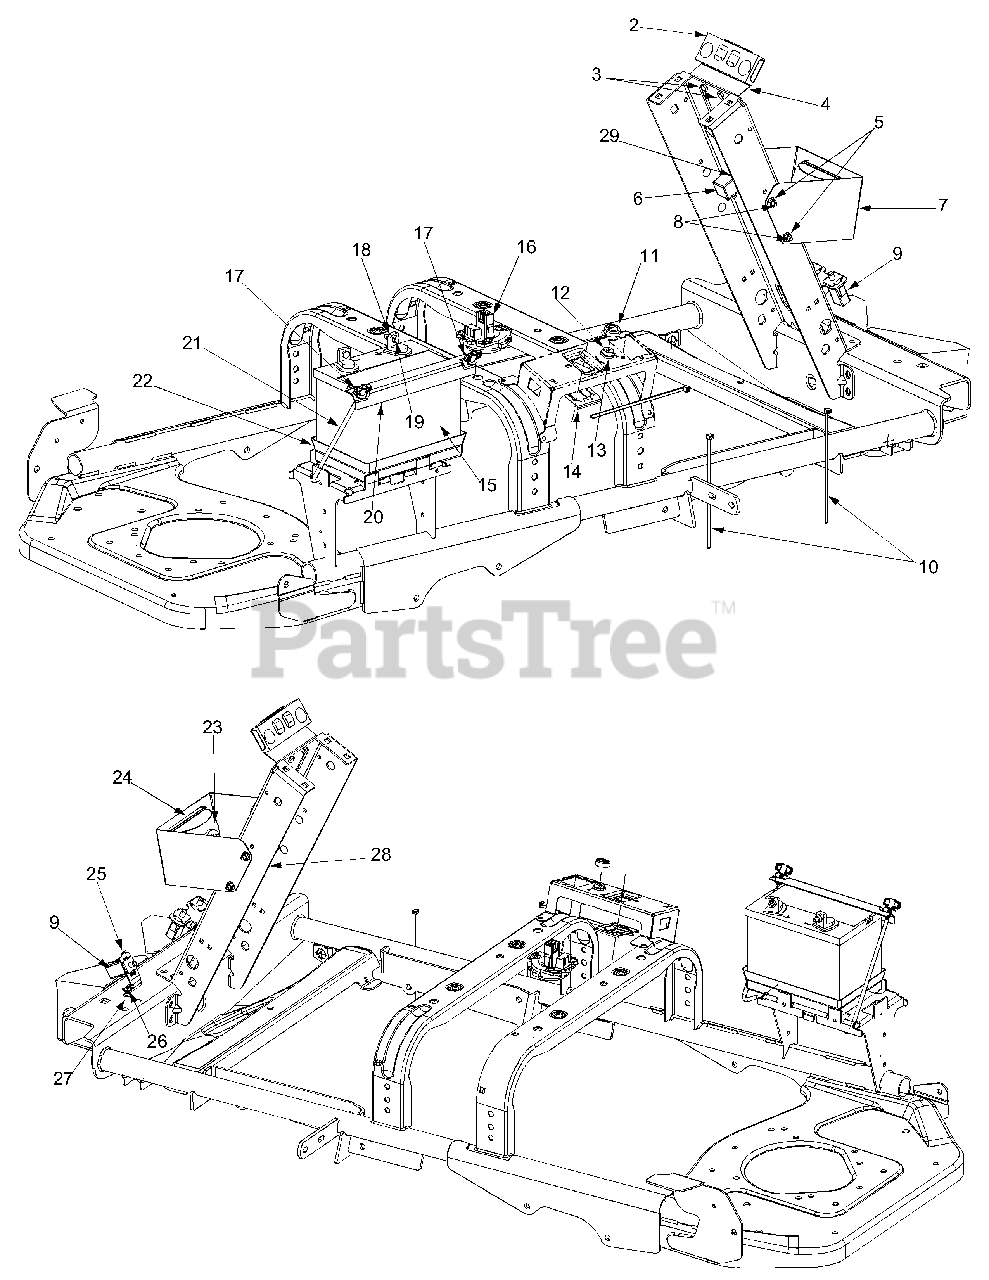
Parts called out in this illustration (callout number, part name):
2	Foam Protector, Indicator Light
3	Hex Cap Screw 1/4-20 x .50
6	Relay
9	Switch, Plunger Safety
11	Cap, Ignition Switch
12	Nut, Ignition Switch, 5/8-32
13	Switch, Ignition
14	Bracket, PTO Switch Retainer
15	Battery
16	Switch, Seat
17	Nut, Nylon Wing, 1/4-20
18	Nut, Hex Sems, 1/4-20
19	Screw, Hex Cap, 1/4-20 x .75 GR5
20	Strip, Battery Retainer
21	Rod, Battery Retainer
22	Tray, Battery
23	Headlight Assembly
23	Bulb, Headlight - Only
24	Bezel, Headlight
25	Spring, Switch Mounting
26	Screw, Machine, #10-24 x 5/8
27	Nut, Hex Insert Lock, #10-24
28	Voltage Sensor
29	Ratchet Retainer
